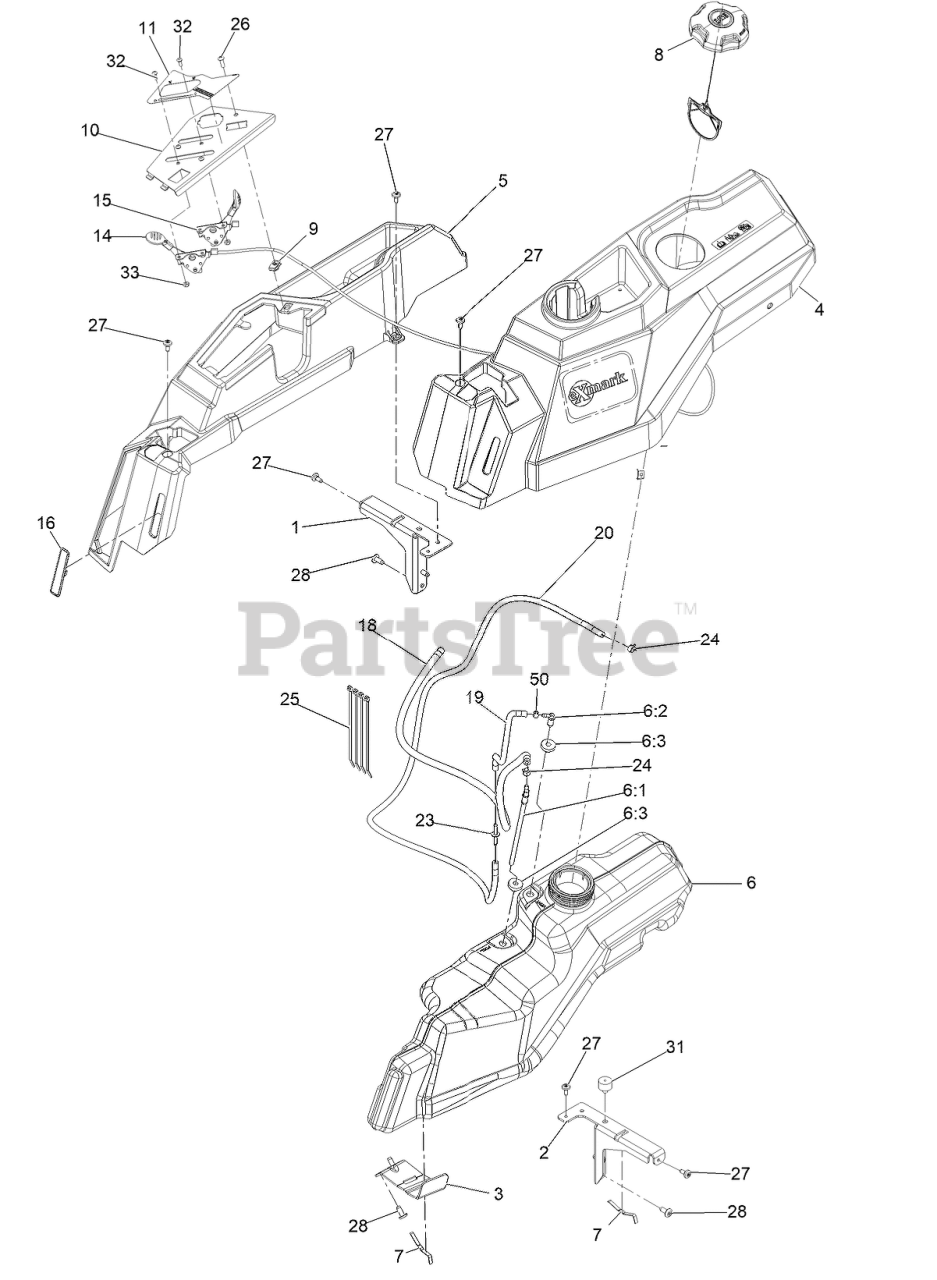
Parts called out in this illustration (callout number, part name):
1	SUPPORT-POD, RH
2	SUPPORT-POD, LH
3	SUPPORT-TANK, FUEL
4	POD- LH
5	POD- RH
6	TANK-FUEL ASM
6:1	Connector-Elbow, 90 DEG
6:2	Fitting-Elbow 90
6:3	BUSHING
7	SPRING
8	CAP-FUEL, RATCHETING
10	PANEL- CONTROL
11	DECAL-CONTROL PANEL
14	ASM,THROTTLE CABLE
15	CABLE-CONTROL, CHOKE
16	PLUG-SC
18	HOSE-FUEL
19	Hose-Fuel
20	Hose-Fuel (.188 X .406 X 40.00)
23	Adapter Orifice
24	CLAMP-HOSE
25	TIE-CABLE
26	SCREW-PRH
27	SCREW-SHOULDER
31	BUMPER-GROMMET
32	SCREW-PPH
33	NUT-LOCK, NI
50	CLAMP-HOSE
